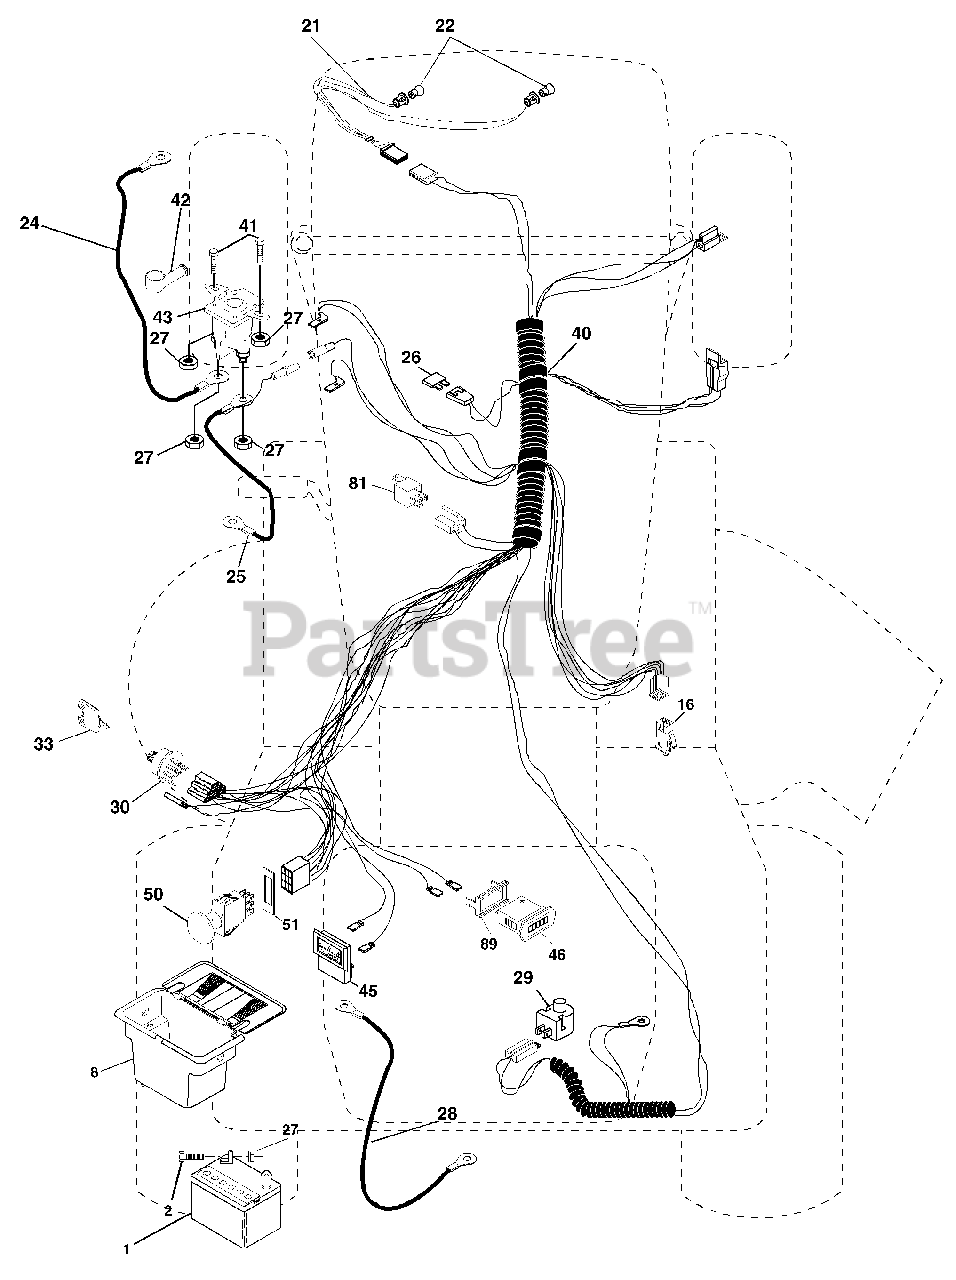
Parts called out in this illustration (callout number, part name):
1	Battery 12 Volt 25 AMP
2	Bolt Hex Hd 1/4-20unc X 3/4
8	Case Battery Mech Hinge
16	Switch Interlock Push-In
21	Harness Asm Light W/4152j
22	Bulb Light #1156
24	Cable Battery 6 Ga 11" red
25	Cable Battery 6 Ga 44" red w/16 wire
27	Nut Keps Hex 1/4-20 Unc
28	Cable Ground 6 Ga 12" black
29	Switch Plunger Nc Gray
30	Switch Ign
33	Key Ign Generic
40	Harness Ign.
41	Bolt Blk Fin Hex 1/4 - 20 x 1/2
42	Cover Terminal Red
43	Solenoid
45	Ammeter Rectangular 15 Amp
46	Meter Hour
50	Switch PTO
51	Ring Retainer PTO
81	Relay Asm.
89	Bracket Snap-In Hourmeter
